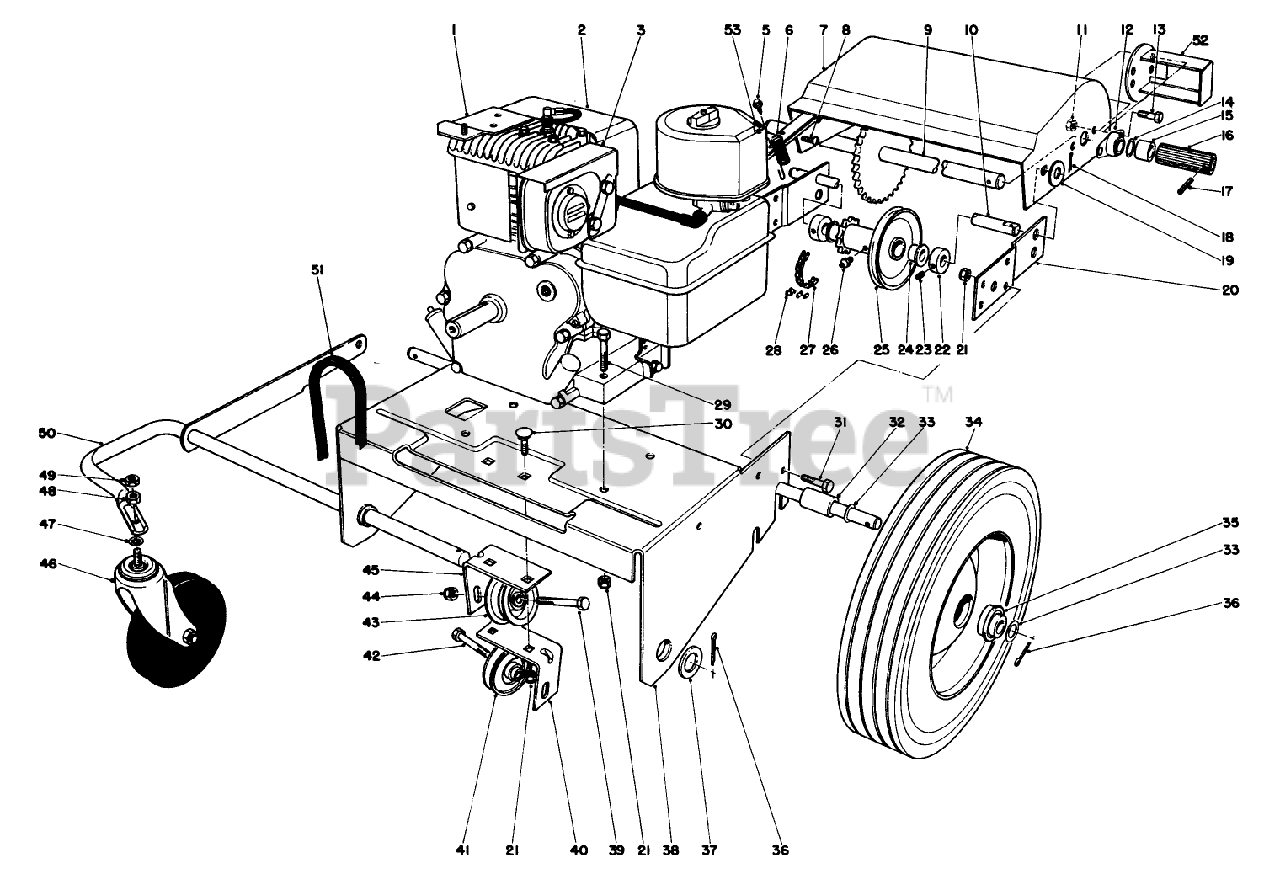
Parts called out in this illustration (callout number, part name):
1	MTG BRKT WA *B
2	Engine
3	HEAT SHIELD
5	SCREW-HH
6	SPRING-TRACTION
8	SCREW-HWH
9	SHAFT-WHEEL, FRICTION
10	SHAFT-IDLER
11	NUT-LOCK, NI
12	BEARING-MOUNT, FLANGE
13	SCREW-HH
14	WASHER
15	SPACER
16	WHEEL-FRICTION
17	PIN-ROLL, SLOTTED
18	PIN-COTTER
19	WASHER-FLAT
21	NUT-LOCK, NI
22	COLLAR
23	SCREW-SET, HSH
24	BUSHING-FLANGE
25	IDLER ASM
26	FITTING-GREASE
27	CHAIN-ROLLER, REEL DRIVE
28	LINK-CONNECTING, NO. 35
29	SCREW-HH
30	SCREW-CARR
31	SCREW-HH
32	SPACER-AXLE
33	WASHER
34	WHEEL
35	BEARING
36	PIN-COTTER
37	WASHER-FLAT
39	SCREW-HH
41	PULLEY-IDLER
42	SCREW-HH
43	PULLEY-IDLER
44	NUT-LOCK, NI
46	CASTER
47	WASHER-LOCK/INT
48	NUT-HH
49	NUT-LOCK, NI
51	V BELT
53	NUT-LOCK, NI
